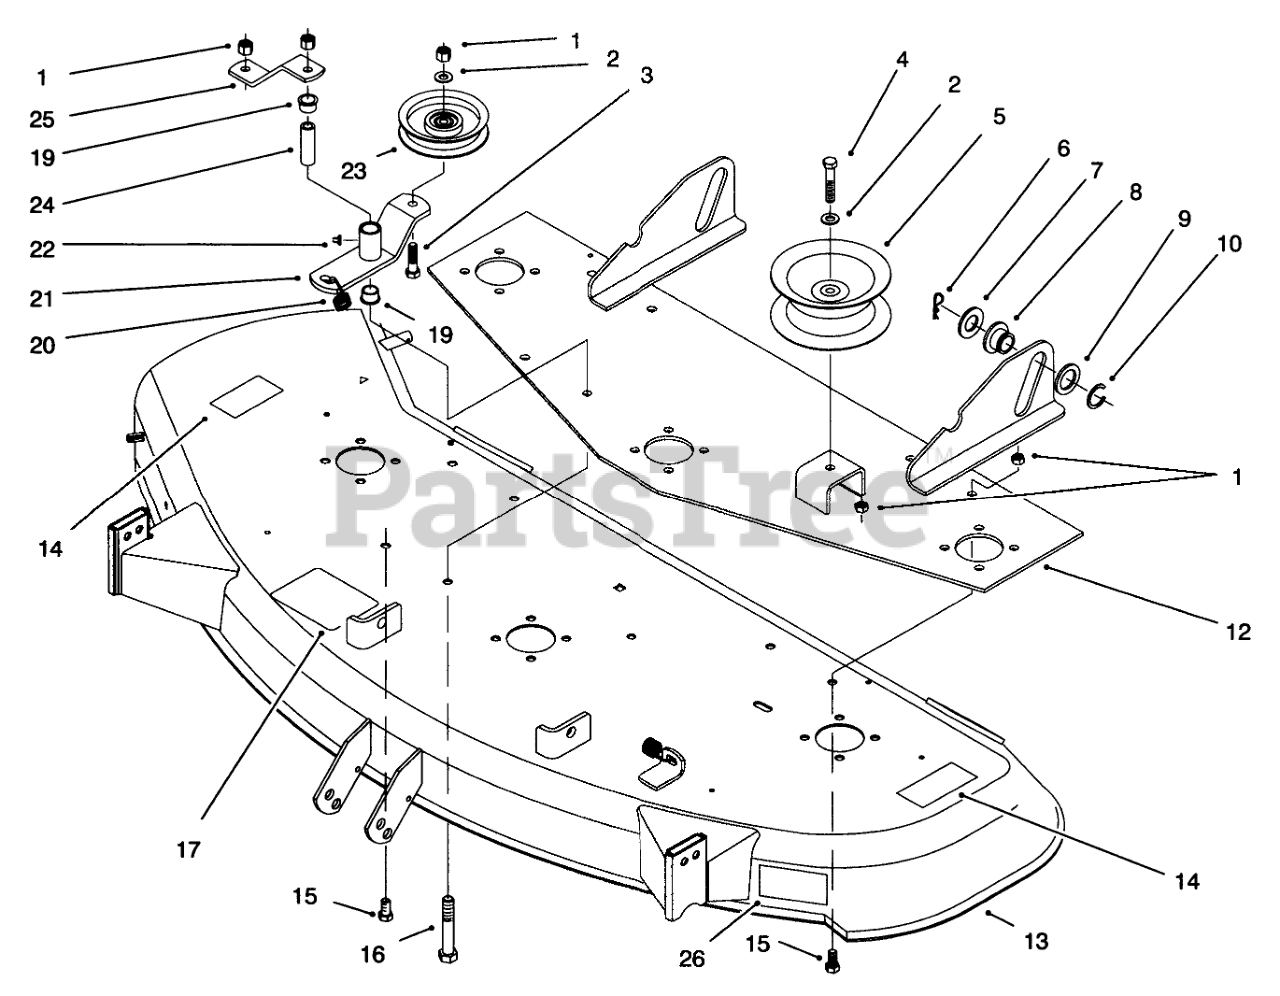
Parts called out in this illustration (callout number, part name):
1	NUT-LOCK, NI
2	WASHER-FLAT
3	SCREW-HH
4	SCREW-HH
5	PULLEY-IDLER
6	PIN-HAIR
7	WASHER-FLAT
8	ROLLER-LIFT
9	WASHER
10	RING-RETAINING
12	Plate-Support
13	Deck & Decal ASM (Incl. Ref. #14)
14	DECAL-DANGER
15	SCREW-HH
16	SCREW-HH
17	DECAL - BELT INSTALLATION
19	BUSHING
20	SPRING - EXTENSION
21	Arm
22	FITTING-GREASE
23	PULLEY-IDLER, FLAT
24	SPACER
25	STRAP-BRACE
26	DECAL-ADJUSTMENT, WHEEL
